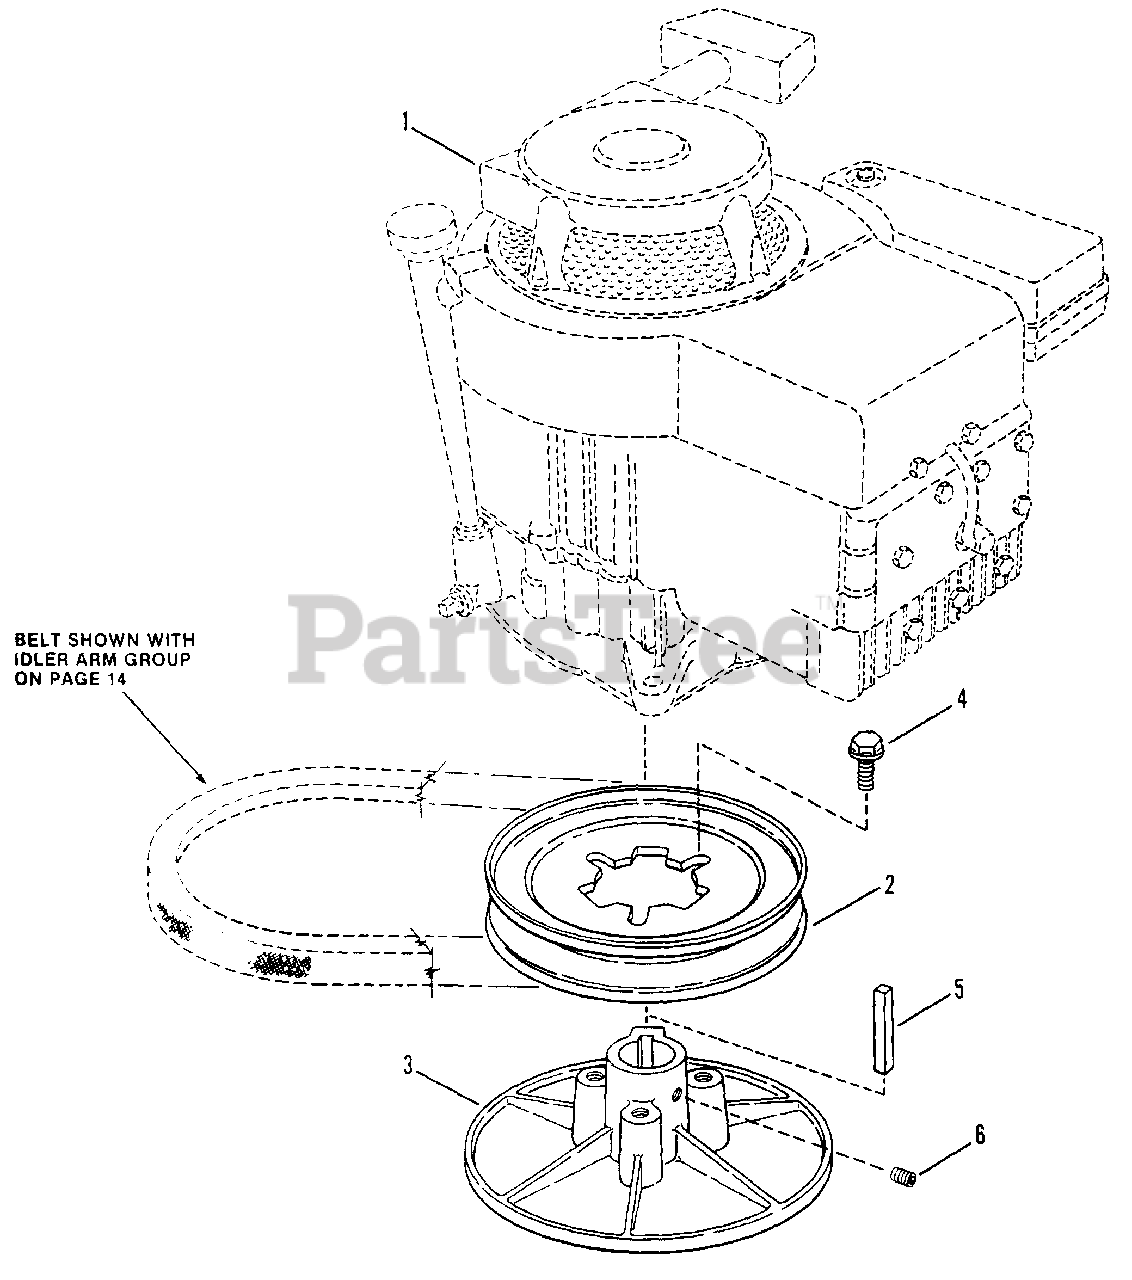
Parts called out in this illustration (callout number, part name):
2	PULLEY, Drive Disc
3	DRIVE DISC
4	SCREW, 1/4-20 x 5/8" Self-Tapping
5	KEY, 1/4 x 1/4 x 2"
6	SETSCREW, 5/16-18 x 5/16" Hex Socket
